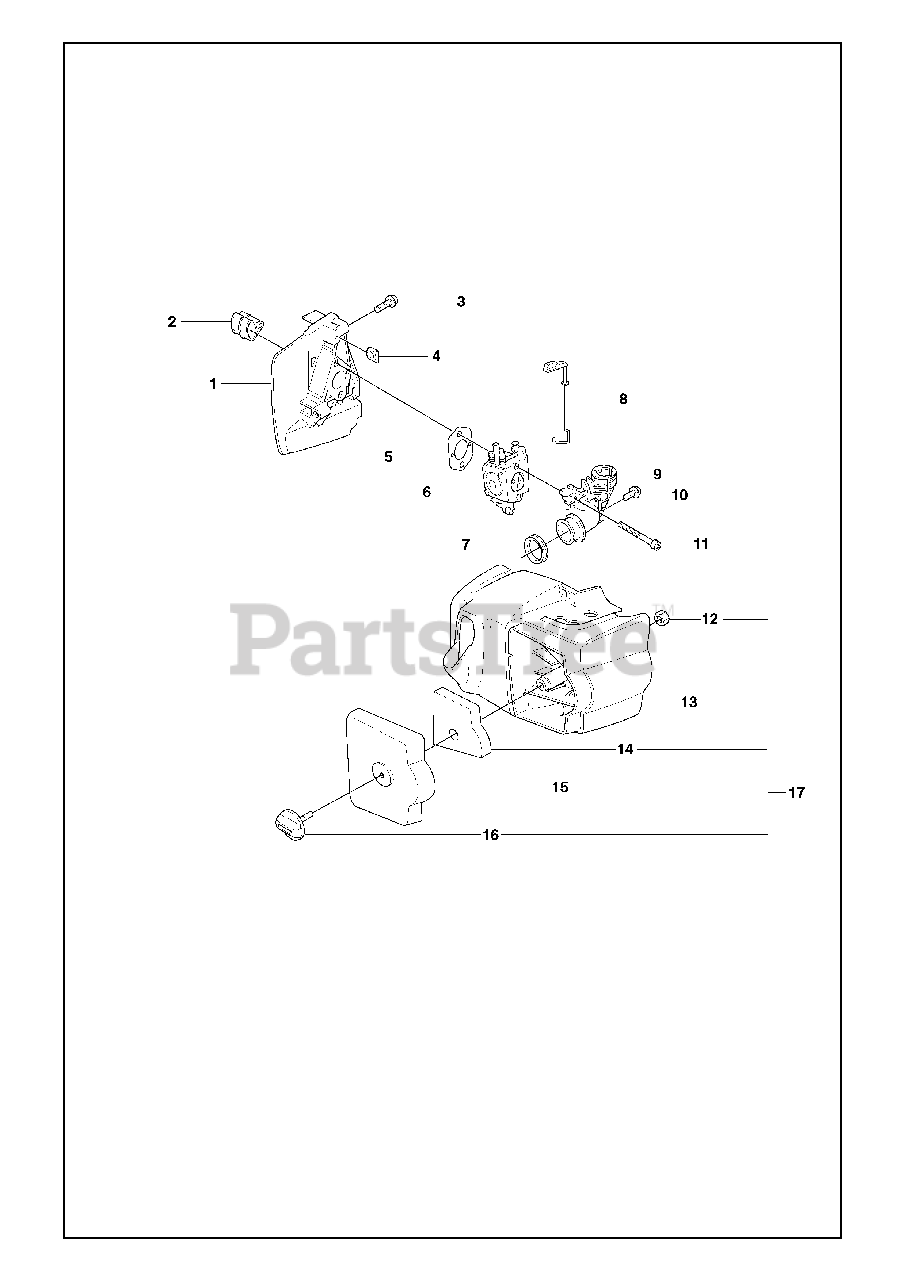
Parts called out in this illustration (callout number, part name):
3	SCREW
6	CARBURETOR
8	CHOKE CONTROL
14	AIR FILTER
15	AIR FILTER COVER
17	CYLINDER COVER ASSY 325
